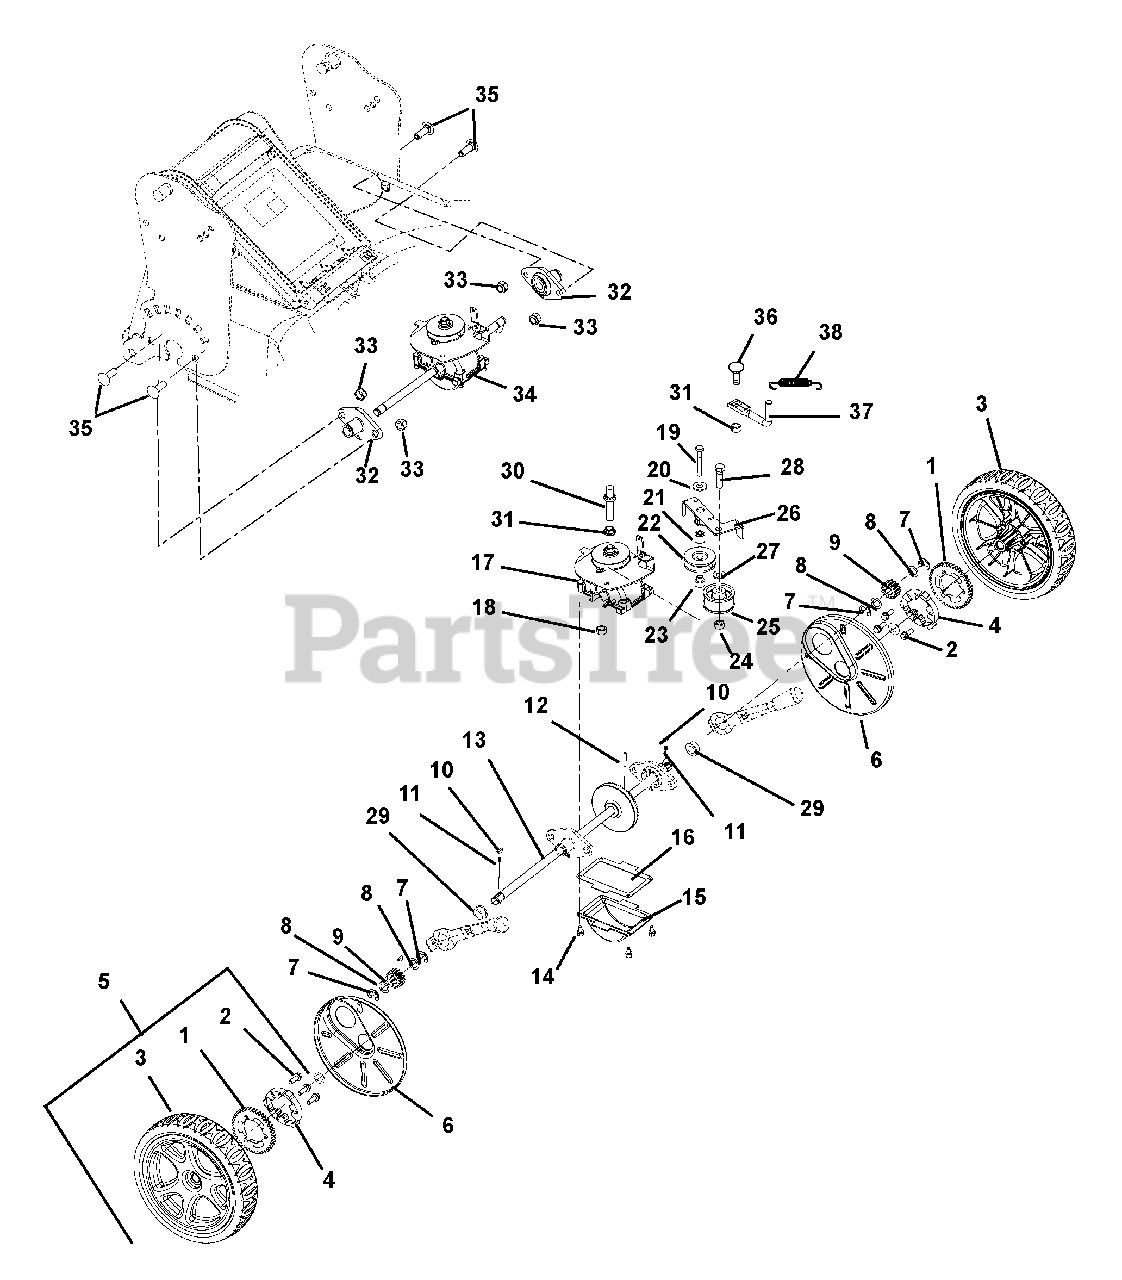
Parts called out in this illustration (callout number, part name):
1	GEAR, WHEEL
2	SCR-TAP .25-15X.75 HI-LO
3	WHEEL, 8.5" WBLM
4	PLATE, WHEEL GEAR TORQUE
5	ASSY, LM REAR WHEEL
6	WHEEL COVER
7	RG-RTNG-EXT .500X.042 (E)
8	WASHER, .500X.750X.020 THRUST
9	PINION, WBLM DRIVE
10	KEY-WDRF .125X.50X.20 (HRDEND)
11	SPRING, .134X.180X.144 COMP.
12	PIN-ROLL .156X1.00
13	SHAFT, TRANSMISSION OUTPUT
14	@SCR-TAP 10-24X.375 HWH YZ TR
15	SUMP, GEARBOX
16	GASKET, TRANSMISSION
17	KIT, WBLM TRANS HOUSING
18	@NUT-LK-TOP-FLG .25-20 YWZC
19	@BLT-HEX .25-20X2.00 GR5 YWZC
20	@WSHR-FL-STL.312X.734X.065 YWZ
21	SPACER, IDLER ARM
22	IDLER, 3L FRONT SIDE .38X1.875
23	SPACER, V-IDLER PULLEY
24	@NUT-LK-CTR .38-16 YWZC
25	IDLER - FLAT 1.875OD X .75WIDE
26	ARM, TRANSMISSION IDLER
27	@WSHR-FL-STL.406X.812X.065 YWZ
28	@BLT-HEX .38-16X1.38 GR5 YWZC
29	BUSHING, TRANS OUTPUT SHAFT
30	FINGER, BELT
31	@NUT-SPNLK-FLG .25-20 YWZC
32	KIT, WHEEL MOUNT HUB SERVICE
33	@NUT-LK-TOP-FLG .31-18 YWZC
34	KIT, TRANSMISSION SERVICE
35	@BLT-RDHDSQNK .31-18X1.00 G5YZ
36	@BLT-RDHDSQNK .25-20X.50 G5YZ
37	FINGER, BELT
38	SG-TENS .051X.60X2.25 WLD 7.0
